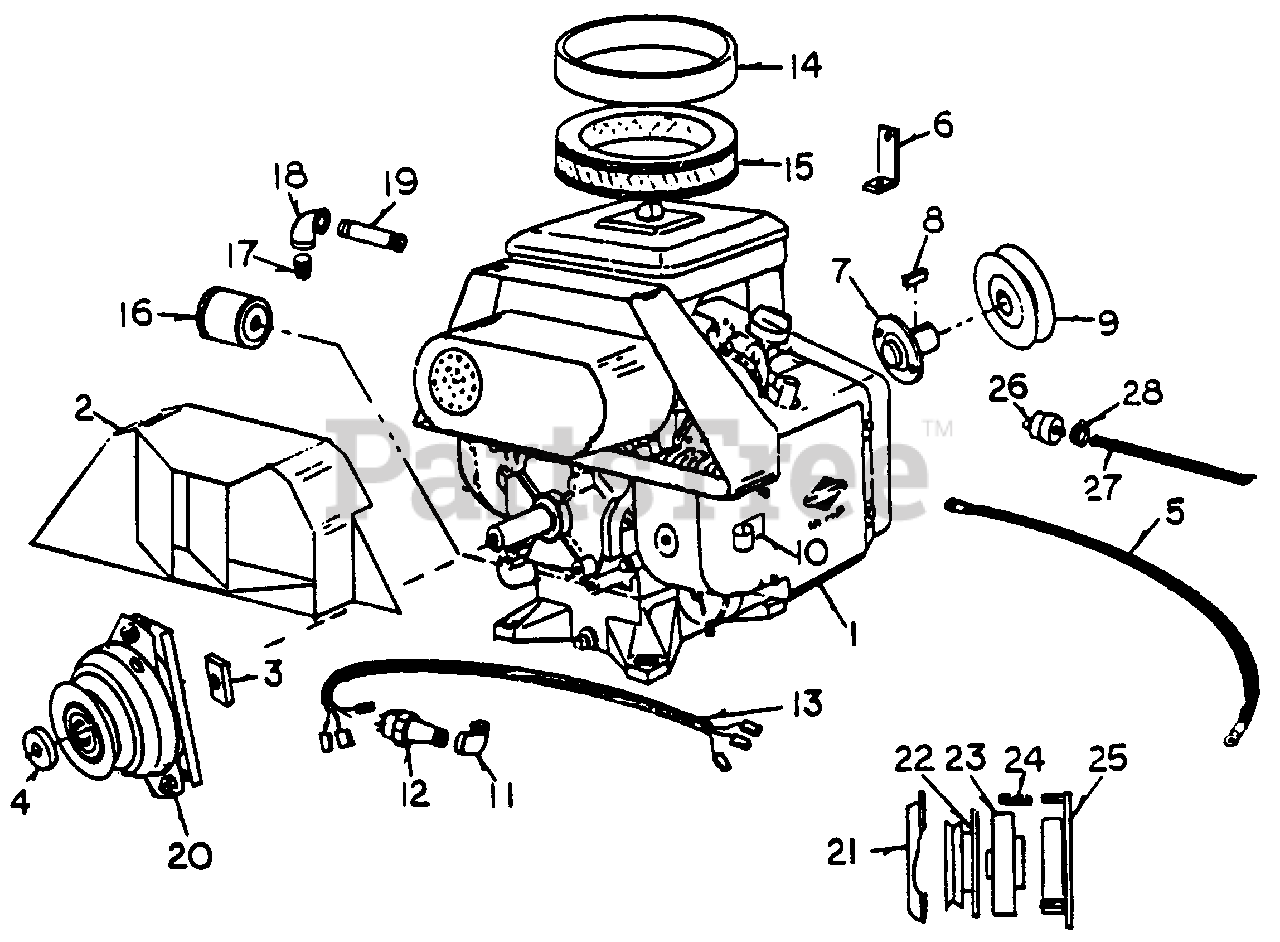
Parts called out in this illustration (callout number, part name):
1	Briggs & Stratton Twin 18 HP
4	Clutch Retainer Washer
6	Wire Standoff
8	Key Stock, 1/4"
10	Starter Cable Retainer
11	Street Elbow, 1/8"
12	0i1 Sending Unit
13	Wire Harness
14	Pre Cleaner
15	Air Cleaner Cartridge
16	0i1 Filter
18	Elbow, 3/8"
19	Nipple, 3/8"
20	Clutch
22	Clutch Armature
23	Clutch Rotor
24	Spring & Nut Set
25	Clutch Coil
26	Fuel Filter
28	Fuel Line Clamp
